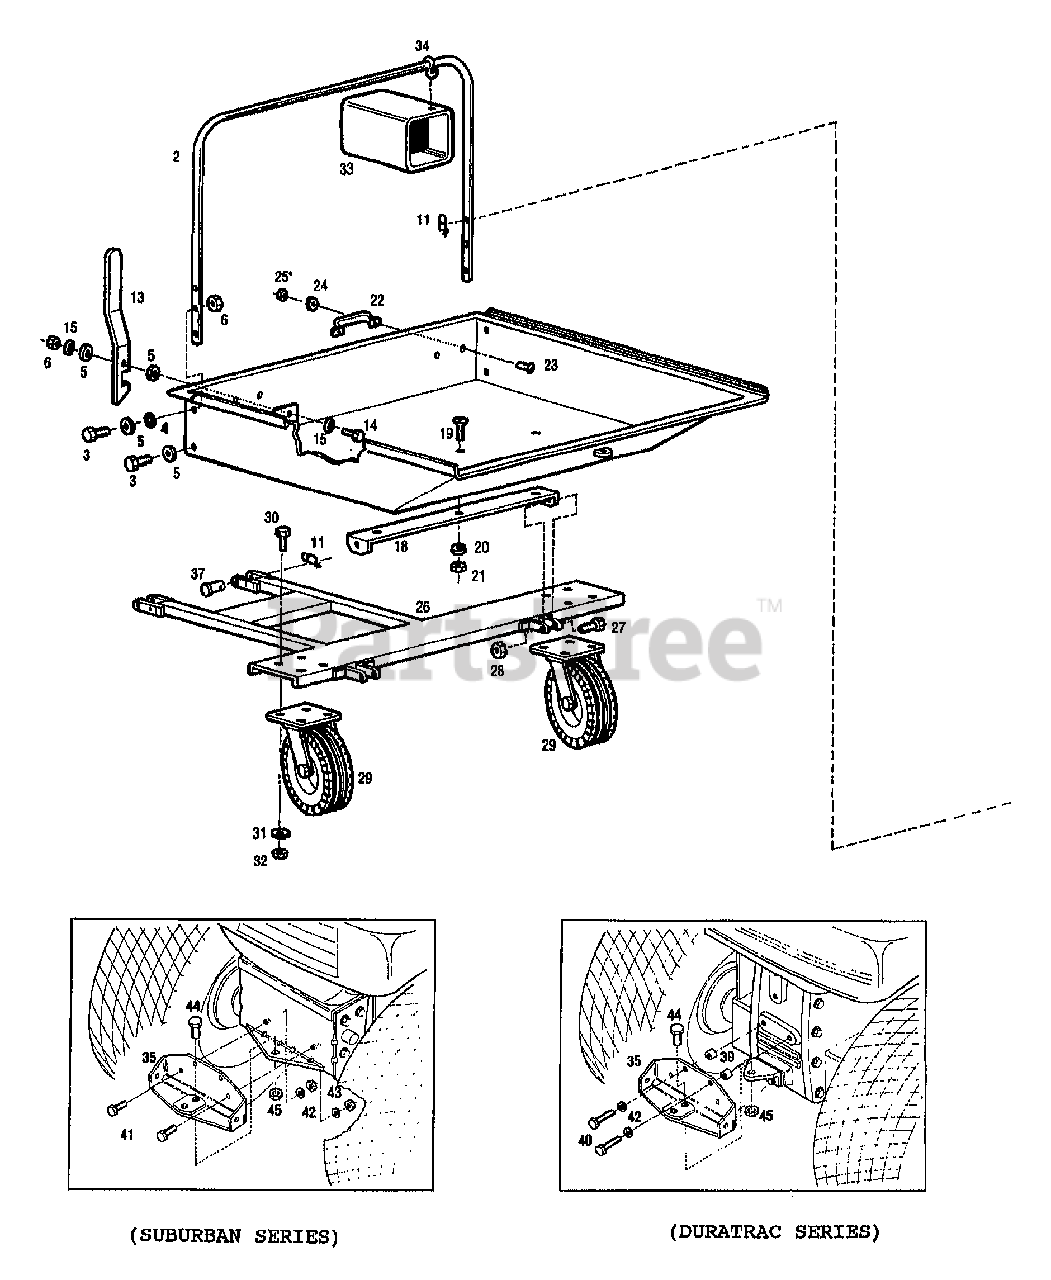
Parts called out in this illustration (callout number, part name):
2	TUBE-SUPPORT
3	SCR-HH 5/16-18X1.5 G5 ZP
4	SPACER
5	WASHER-FLAT 5/16 SAE
6	NUT-TOP/LK 5/16-18 ZP
11	RING-COTTER
13	HANDLE-LATCH
14	SCR-HH 5/16-18X1.0 G5 ZP
15	WASHER
19	SCR-5/16-18X1.00
20	WASHER-LK .312 ZP
21	NUT-HEX 5/16-18 ZP
22	HANDLE-LIFT
23	SCR 1/4-20X.5 TRUSS HD
24	WASHER-LK .25 ZP
25	NUT-HEX 1/4-20 ZP
27	SCR-HH 1/2-13X1.25 G5 ZP
28	NUT-TOP LOCK 1/2-13 ZP
30	SCR-HH 3/8-16X1.0 G5 ZP
31	WASHER-FLAT 3/8 SAE
32	NUT-LOCK 3/8-16
33	SLEEVE
34	ASSM-SLEEVE CLAMP
35	PLATE-MOUNTING GRASSBAG
37	PIN-CLEVIS .5X1.25
39	SPACER-.75X.531X.89
40	SCR-HH 1/2-13X1.75 G5 ZP
41	SCR-HH 1/2-13X1.0 G5 ZP
42	WASHER-LK .5
43	NUT-HEX JAM 1/2-13
45	NUT-H/LK 3/4-10
